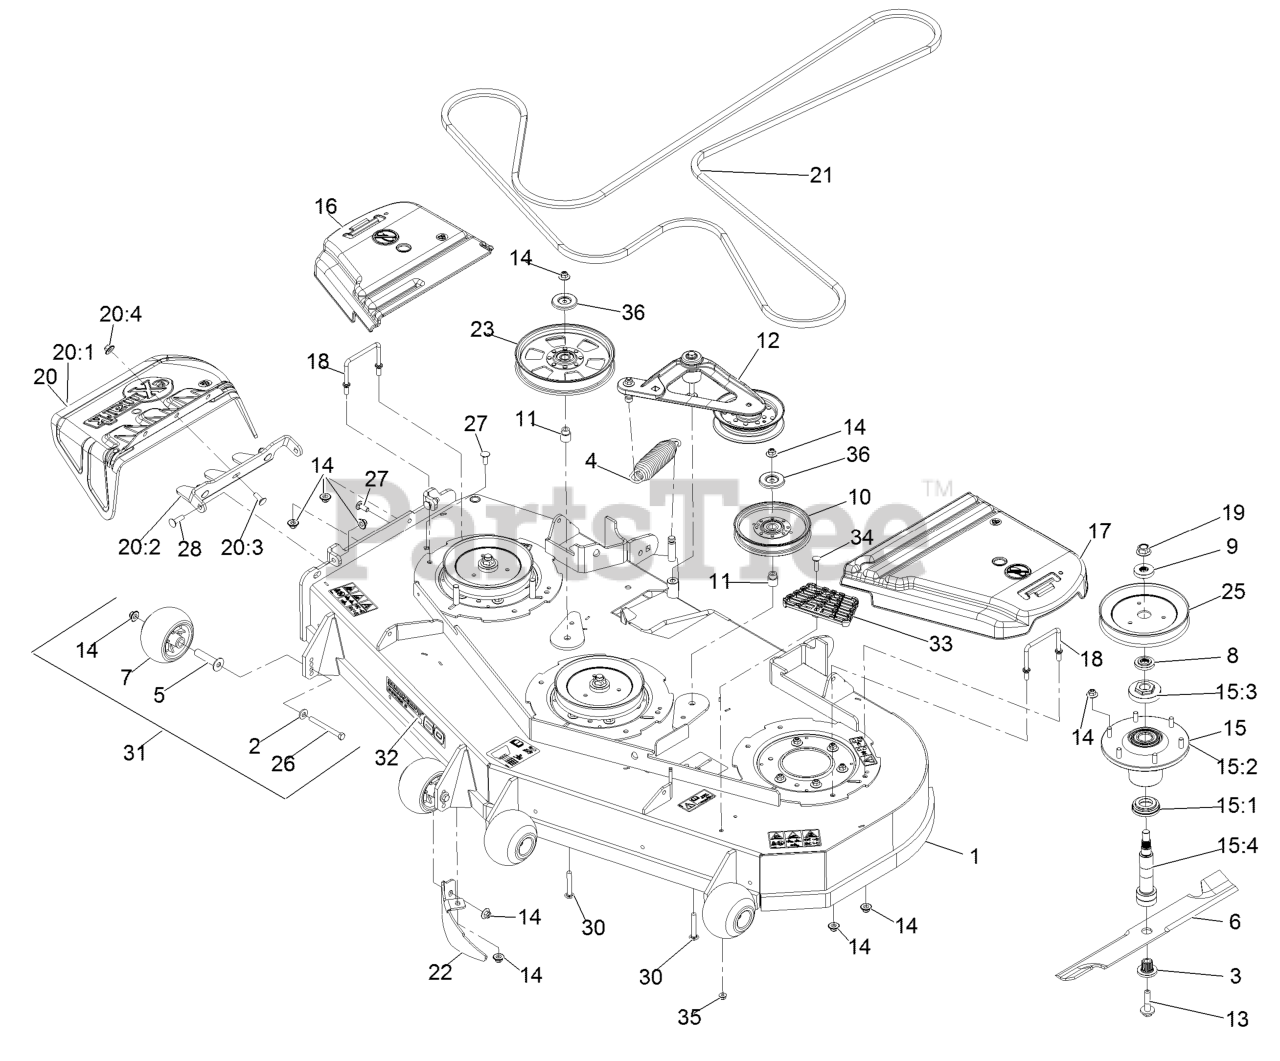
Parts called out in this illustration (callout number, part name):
1	DECK ASM,W/DECALS 60
2	WASHER-BELLEVILLE
3	BUSHING,SPLINED
4	SPRING-EXTENSION
5	AXLE, ROLLER
6	Blade-Extreme 2, 20.50"
7	ROLLER-SCALP, ANTI
8	SPACER,SPLINED STEPPED
9	SPACER,SPLINED
10	IDLER-PULLEY
11	BUSHING-IDLER
12	DECK IDLER ASM
13	SCREW,SEMS 1/2-20 X 2.19
14	Nut-Nyloc 3/8-16 Flg
15	ASM,SPINDLE HOUSING
15:1	GUARD,BOTTOM
15:2	ASM,CUTTER HOUSING
15:3	NUT, SPINDLE 7/8-14
15:4	SPINDLE,DOUBLE SPLINE
16	COVER-BELT, RH
17	COVER-BELT, LH
18	WIREFORM-COVER
19	NUT-FLANGE, CENTERLOCK
20	ASM,DISCHARGE CHUTE
20:1	CHUTE,DISCHARGE
20:2	BRACKET,DISCHARGE CHUTE
20:3	SCREW-CARR
20:4	Nut-Nyloc 3/8-16 Flg
21	BELT,V-5V-198.75
22	DOGLEG - LZ60
23	PULLEY-IDLER, FLAT
25	SHEAVE,BLADE DRIVE 7.25
26	SCREW-HH 3/8-16 X 3 3/4 GR 8
27	SCREW-CARR
28	Bolt-Carriage 3/8-16 X 1 1/4
30	SCREW-CARR
31	KIT, ANTI-SCALP ROLLER
32	DECAL, 606
33	STEP-DECK
34	Bolt-Carriage 5/16-18 X 1 1/4
35	NUT-HF, NI
36	SHIELD-DUST
